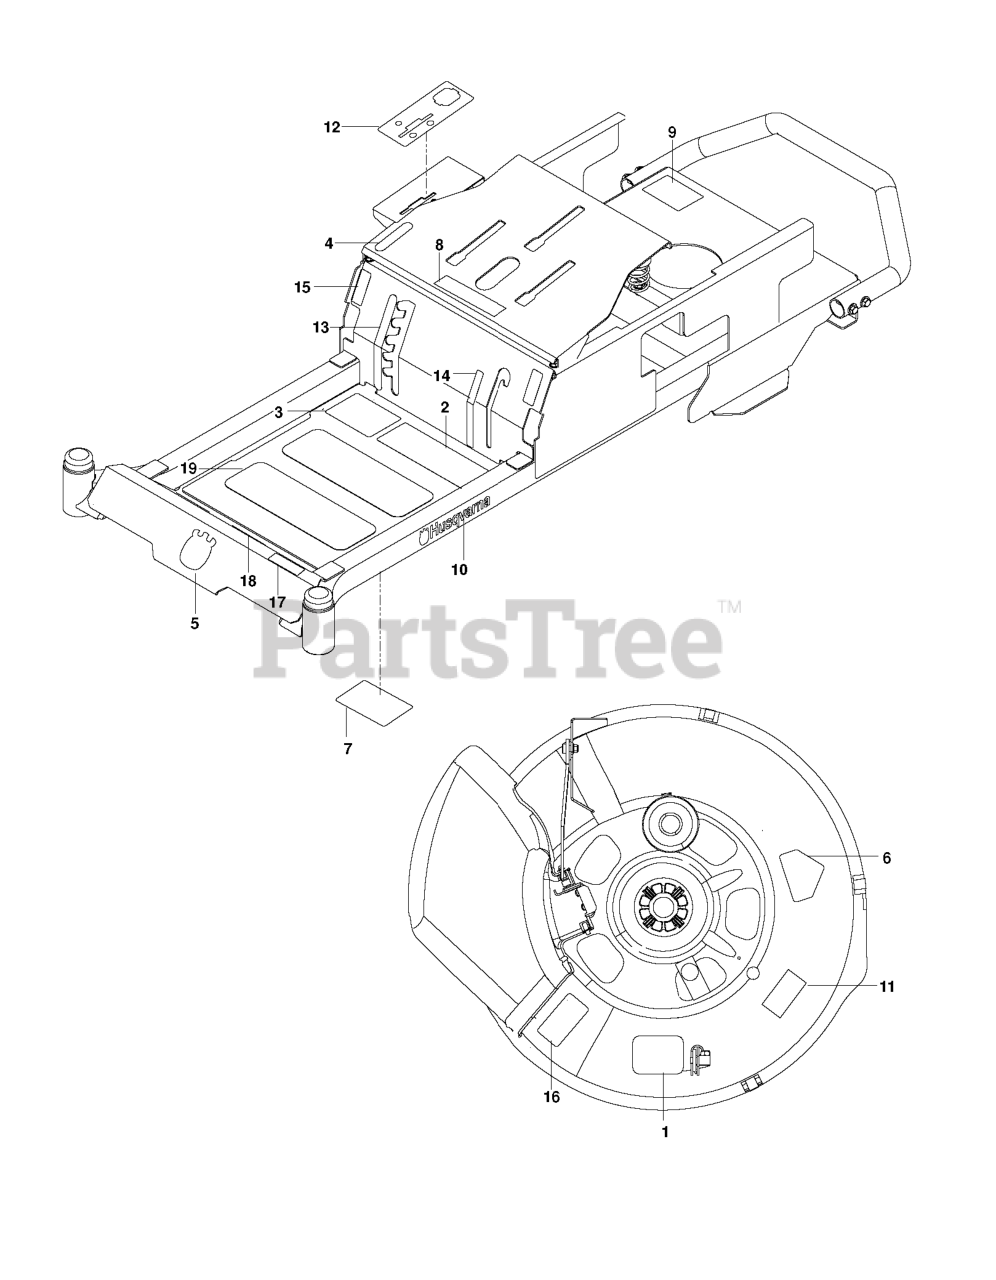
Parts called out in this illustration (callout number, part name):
1	DECAL, BELT ROUTING
2	DECAL, SAFETY WARNING
3	DECAL ZTR STARTING
4	DECAL, PARK BRAKE
5	DECAL.AUGER.HUSQ.CROWN.SNOW
6	DECAL, DECK DEFLECTOR, WARNING
7	DECAL, SERVICE
8	EURO DECAL-BATTERY WARNIN6
9	DECAL, DO NOT TOW
10	RP.DECAL.BADGE.170MM.TEXTLOGO
11	DECAL, EURO SEVERING
12	DECAL.ZTR.CONTROL.PANEL
13	DECAL, DECK HEIGHT
14	DECAL, BLADE ENGAGEMENT
15	DECAL, MOTION CONTROL
16	DECAL.DECK.6MIL./DEF.SHLD.WARN
17	DECAL, RZ3016
18	ANTI-SKID PAD
